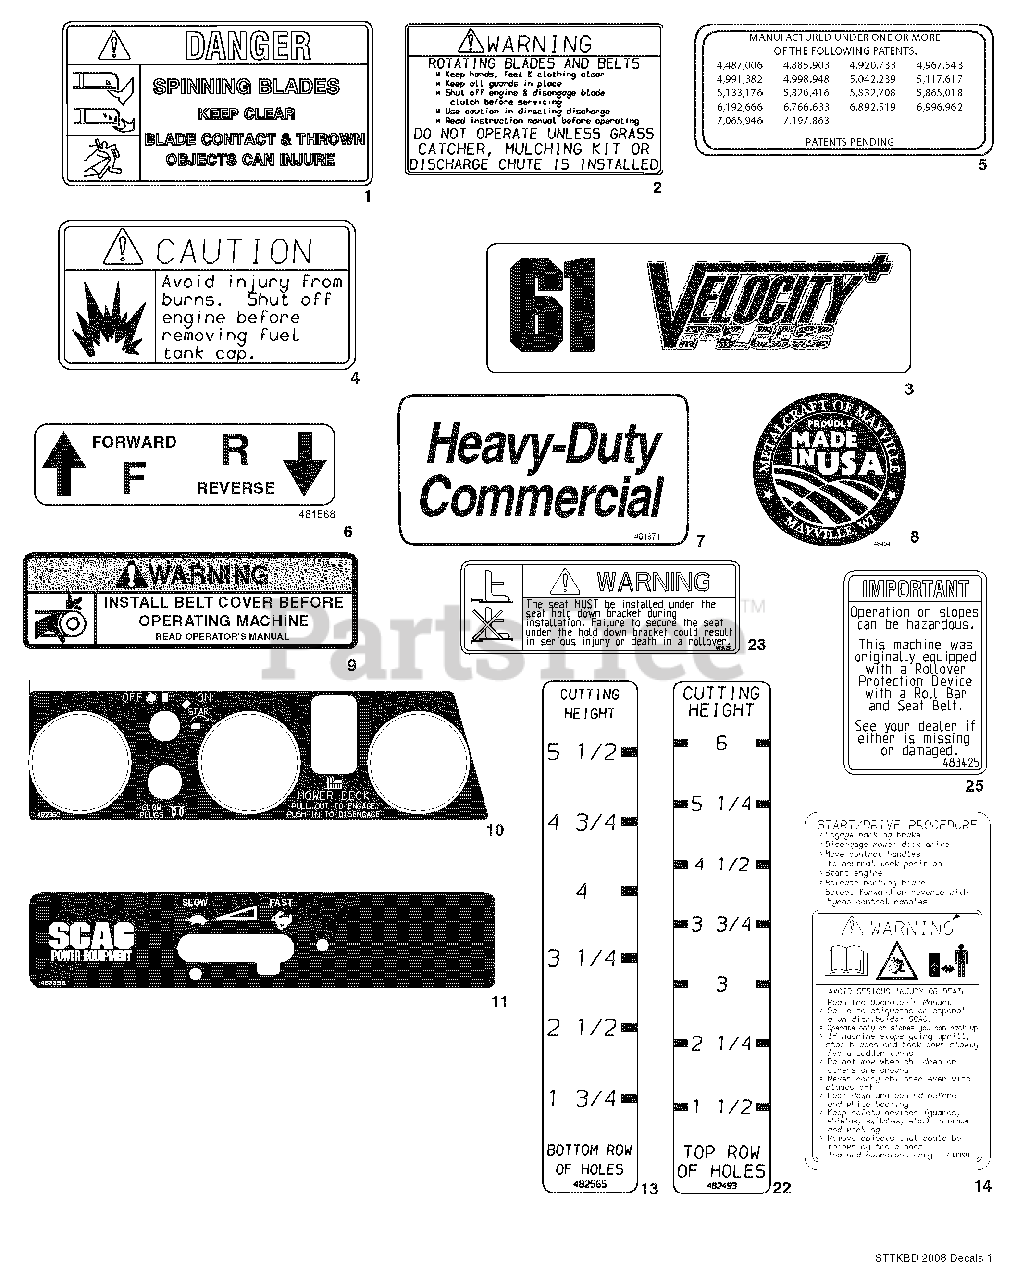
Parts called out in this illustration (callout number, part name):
1	Decal, Danger-Spinning Blades
2	Decal, Warning-Rotating Blades
3	Decal, 61 Velocity Plus
4	Decal, Fuel Tank
5	Decal, Patents
6	Decal, Traction Control
7	Decal, Heavy Duty Commercial
8	Decal, Metalcraft-Made In USA
9	Decal, Belt Cover
10	Decal, Instrument Panel-Upper
11	Decal, Instrument Panel - Lower
13	Decal, Cutting Height - Lower
14	Decal, Start/Drive Procedure
22	Decal, Cutting Height - Upper
23	Decal, Warning Seat Hold Down
25	Decal, ROPS
